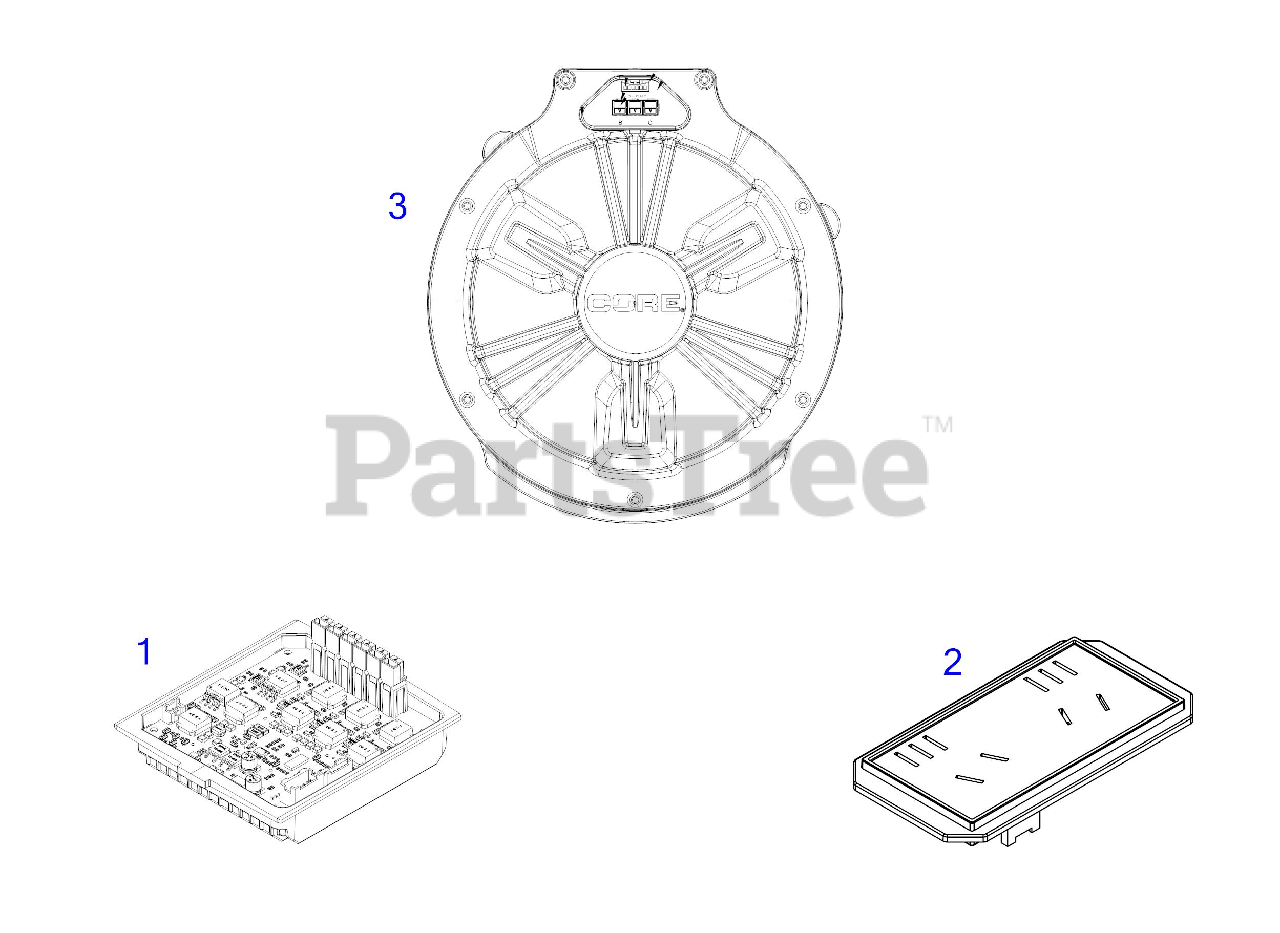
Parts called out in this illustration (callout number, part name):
1	CONTROLLER ASSEMBLY CORE MOWER 700
2	OPERATORS PANEL ASM CORE MOWER
3	MOTOR ASSEMBLY CORE MOWER
